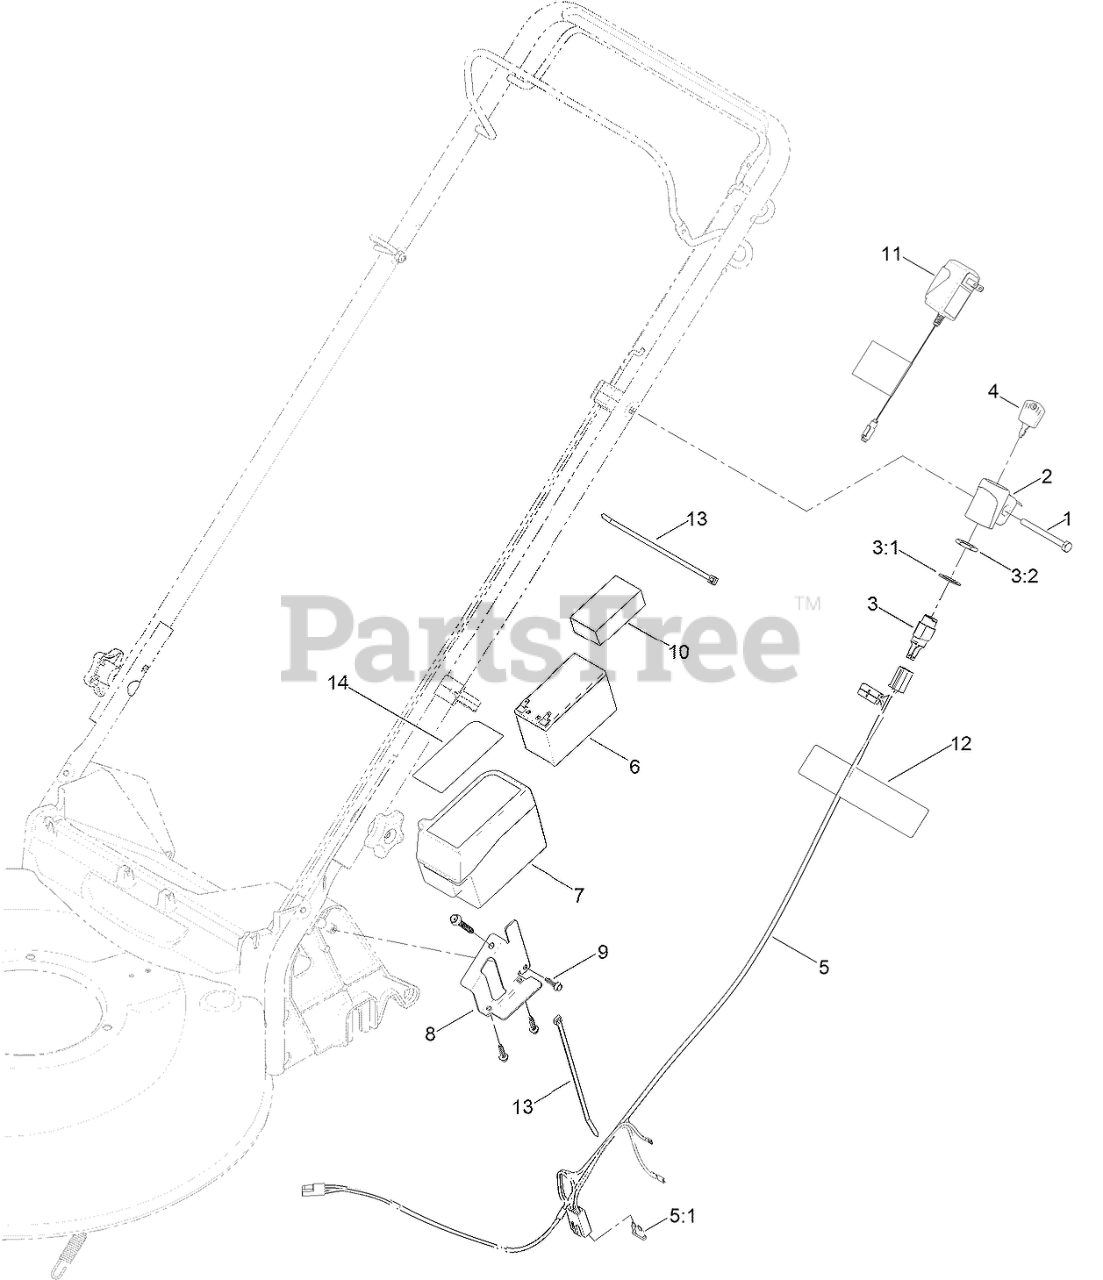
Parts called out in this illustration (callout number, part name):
1	SCREW-HH
2	MOUNT-SWITCH
3	STARTER SWITCH ASM
3:1	WASHER-TOOTH, INTERNAL
3:2	NUT-HH
5	HARNESS-WIRE
5:1	FUSE-40 AMP
6	BATTERY-NONSPILLABLE, 12 V
7	BATTERY BOX ASM
8	BRACKET-BATTERY
9	SCREW-HWH
10	FOAM-BATTERY, TOP
11	CHARGER-CE
12	DECAL-WARNING
13	TIE-CABLE
14	DECAL-BATTERY BOX
